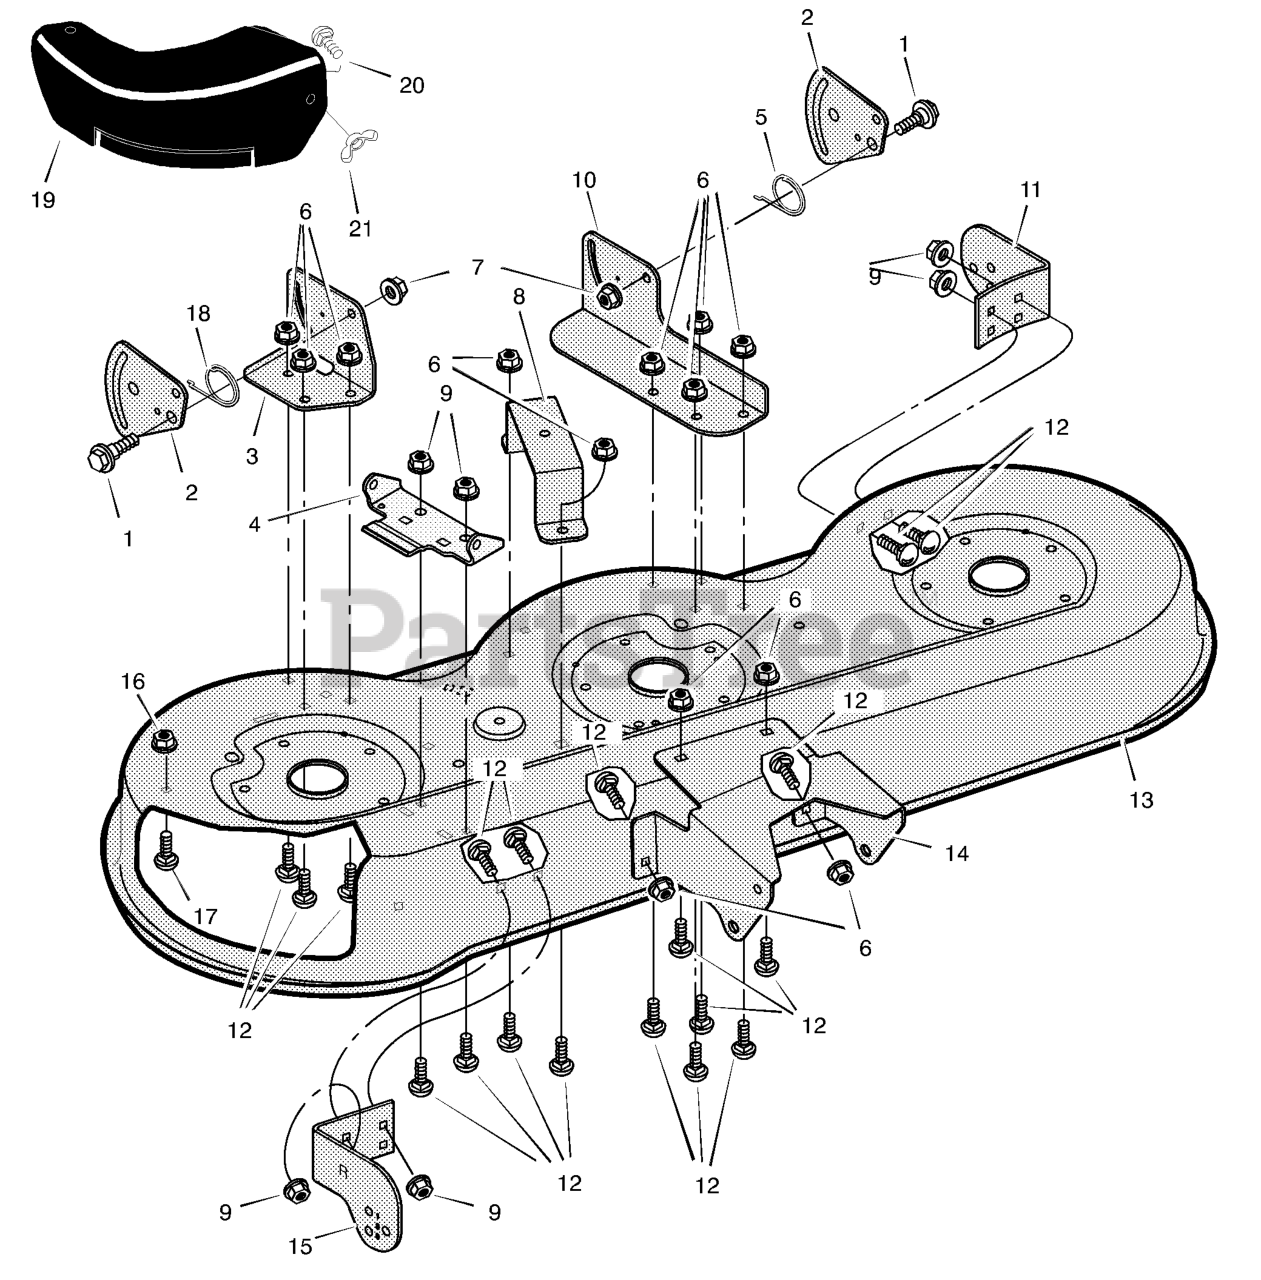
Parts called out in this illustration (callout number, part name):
1	Bolt, Shoulder
2	Plate, Suspension
3	Bracket, Right Rear
4	Bracket, Hinge
5	Spring, Left
6	Nut, Flange
7	Nut, Flange
8	Bracket, Bell Crank
9	Nut, Flange
10	Bracket, Left Lifter
11	Bracket, Left Gauge Wheel
12	Bolt, Carriage
13	Housing, Blade
14	Bracket, Front Deck
15	Bracket, Right Gauge Wheel
16	Retainer
17	Bolt, Carriage
18	Spring, Right
19	Cover, Mulcher
20	Bolt, Carriage
21	Wingnut
